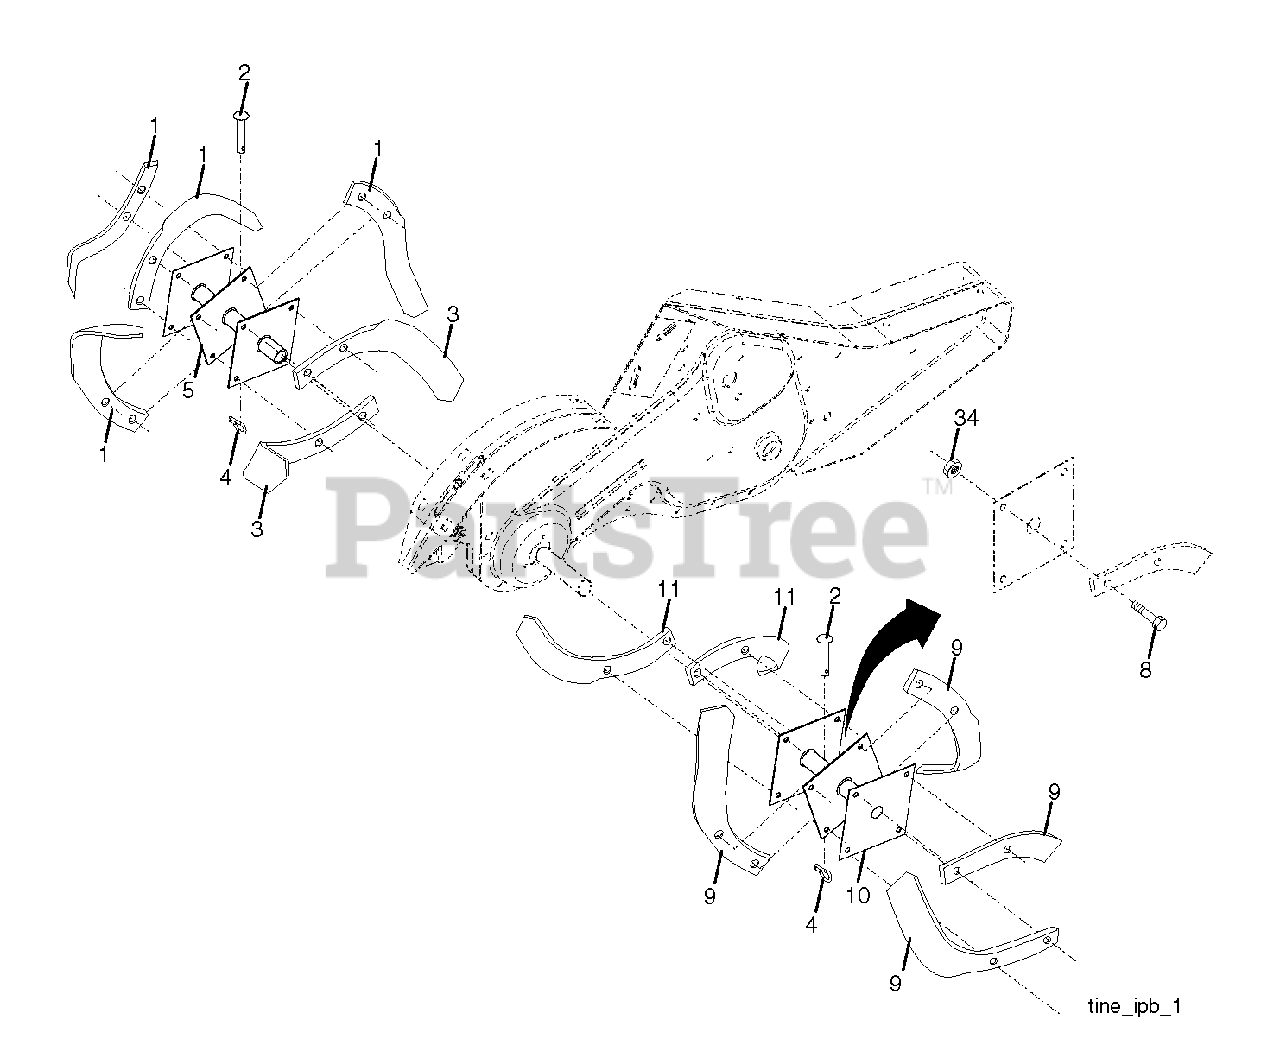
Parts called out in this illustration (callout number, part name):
1	TINE TI
2	CLEVIS PIN
3	TINE.LH.12"
4	SPRING RETAINER
5	HUB & PLATE ASM LH
8	BOLT.HEX.001X20.37-24X1.ZINC
9	TINE TI
10	HUB & PLATE ASM RH
11	TINE.RH.12"(72R)
34	NUT CROWNLOCK 3/8-24
